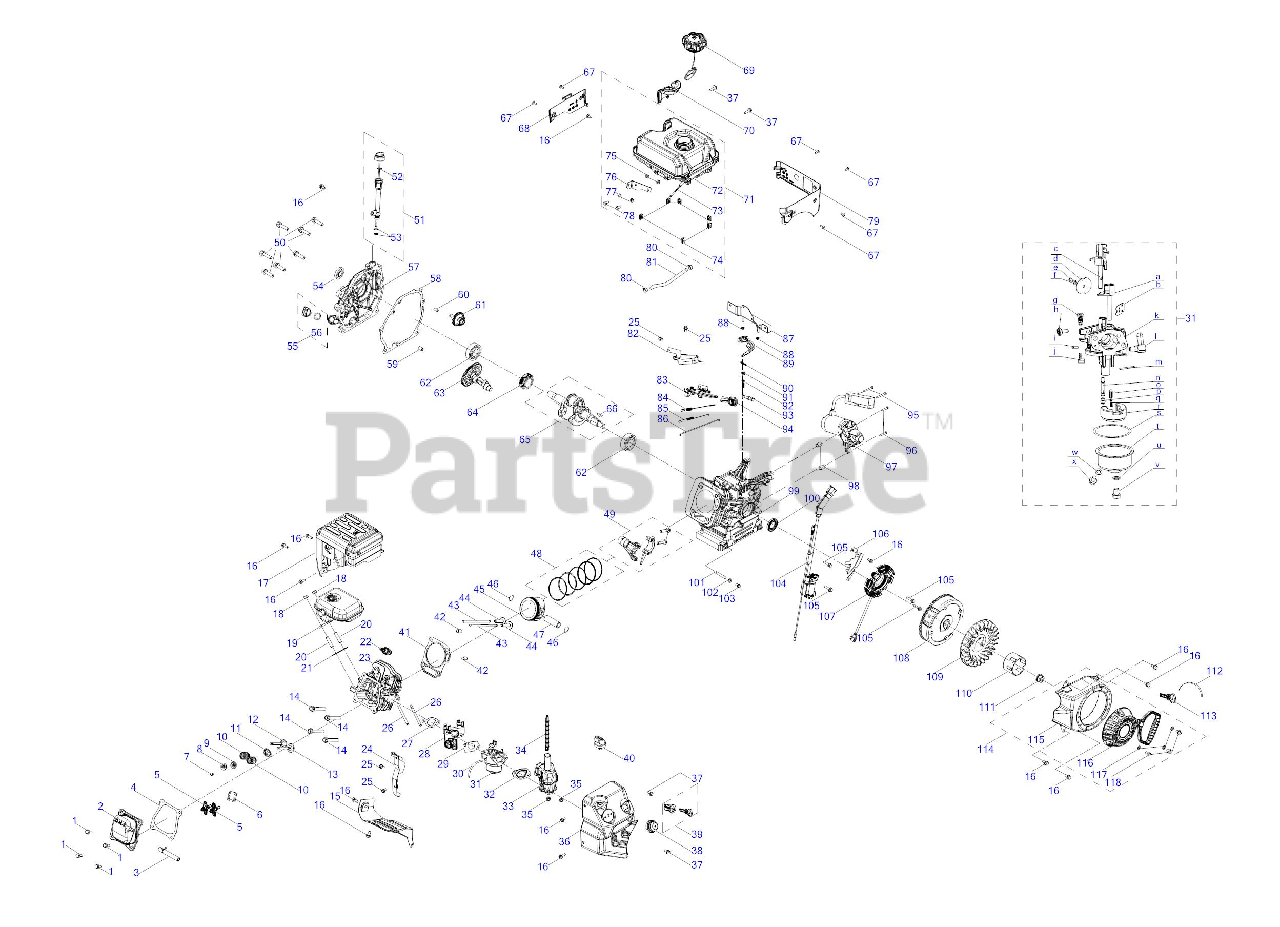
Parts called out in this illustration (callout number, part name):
1	BOLT M6-1 x 16 GR8.8
2	VALVE COVER
3	BREATHER HOSE
4	VALVE COVER GASKET
5	ROCKER ARM ASSEMBLY
6	ROCKER ARM BASE
7	EXHAUST VALVE ADJUSTER
8	EXHAUST VALVE SPRING RETAINER
9	INTAKE VALVE SPRING RETAINER
10	VALVE SPRING
11	INTAKE VALVE SEAL
12	EXHAUST VALVE
13	INTAKE VALVE
14	BOLT M8-1.25 x 55 GR10.9
15	AIR SHIELD
16	BOLT M6-1 x 12 GR8.8
17	MUFFLER GUARD
20	STUD M8-1.25 x 34
21	MUFFLER GASKET
22	SPARK PLUG
23	CYLINDER HEAD
24	SNOW GUARD
25	BOLT M6-1 x 12 GR8.8
26	STUD M6 X 90
27	CARBURETOR INSULATOR GASKET
29	CARBURETOR GASKET
30	PRIMER HOSE
31	CARBURETOR ASSEMBLY
32	CARBURETOR GASKET PLATE
33	HEATER BOX
34	CHOKE LINKAGE
36	CONTROL PANEL
37	BOLT M6-1 x 18 GR8.8
39	ENGINE KEY SWITCH ASSEMBLY
40	CHOKE LEVER
41	CYLINDER HEAD GASKET
43	PUSH ROD
46	PISTON PIN SNAP
47	PISTON PIN
48	PISTON RING SET
49	CONNECTING ROD
50	BOLT M8-1.25 x 32 GR5.8
51	DIPSTICK ASSEMBLY
52	DIPSTICK O-RING
53	OIL FILL TUBE O-RING
54	OIL SEAL
56	O-RING 15.8 x 2
57	CRANKCASE COVER
58	CRANKCASE COVER
59	DOWEL PIN
60	DOWEL PIN
61	GOVERNOR GEAR/SHAFT ASSEMBLY
64	DRIVE TIMING GEAR
65	CRANKSHAFT
66	FLYWHEEL KEY
67	BOLT: M5 x 14
68	DECORATIVE SHEET: RIGHT
70	DECORATIVE COVER
73	FUEL FILTER
74	FUEL TANK MOUNT THREADED TAB
76	FUEL TANK MOUNT TAB
77	WASHER 6.5 X 1.5 X 12
78	BOLT M6 X 20
79	DECORATIVE SHEET: LEFT
80	HOSE CLAMP
81	FUEL HOSE 6.3 X 12.5 X 162
82	GOVERNOR SHIELD
83	GOVERNOR GEAR BRACKET ASSEMBLY
84	GOVERNOR SPRING
85	THROTTLE SPRING
86	GOVERNOR ROD
87	FUEL TANK BRACKET
89	GOVERNOR LEVER
90	COTTER PIN
91	GOVERNOR SEAL
93	GOVERNOR SHAFT
94	THROTTLE KNOB
96	BOLT M6-1 x 32 GR8.8
97	ELECTRIC STARTER
98	DOWEL PIN
100	OIL SEAL
101	OIL DRAIN PIPE
102	WASHER
103	OIL DRAIN PLUG
104	IGNITION MODULE
105	BOLT M6-1 x 25 GR8.8
106	BLOWER SHIELD
107	IGNITION MODULE
108	FLYWHEEL
109	COOLING FAN
110	STARTER CUP
111	FLYWHEEL NUT
113	IGNITION KEY
114	RECOIL STARTER
115	BLOWER HOUSING
116	RECOIL STARTER ASSEMBLY
117	RECOIL FLAT WASHER
118	BOLT M6 x 10 GR8
